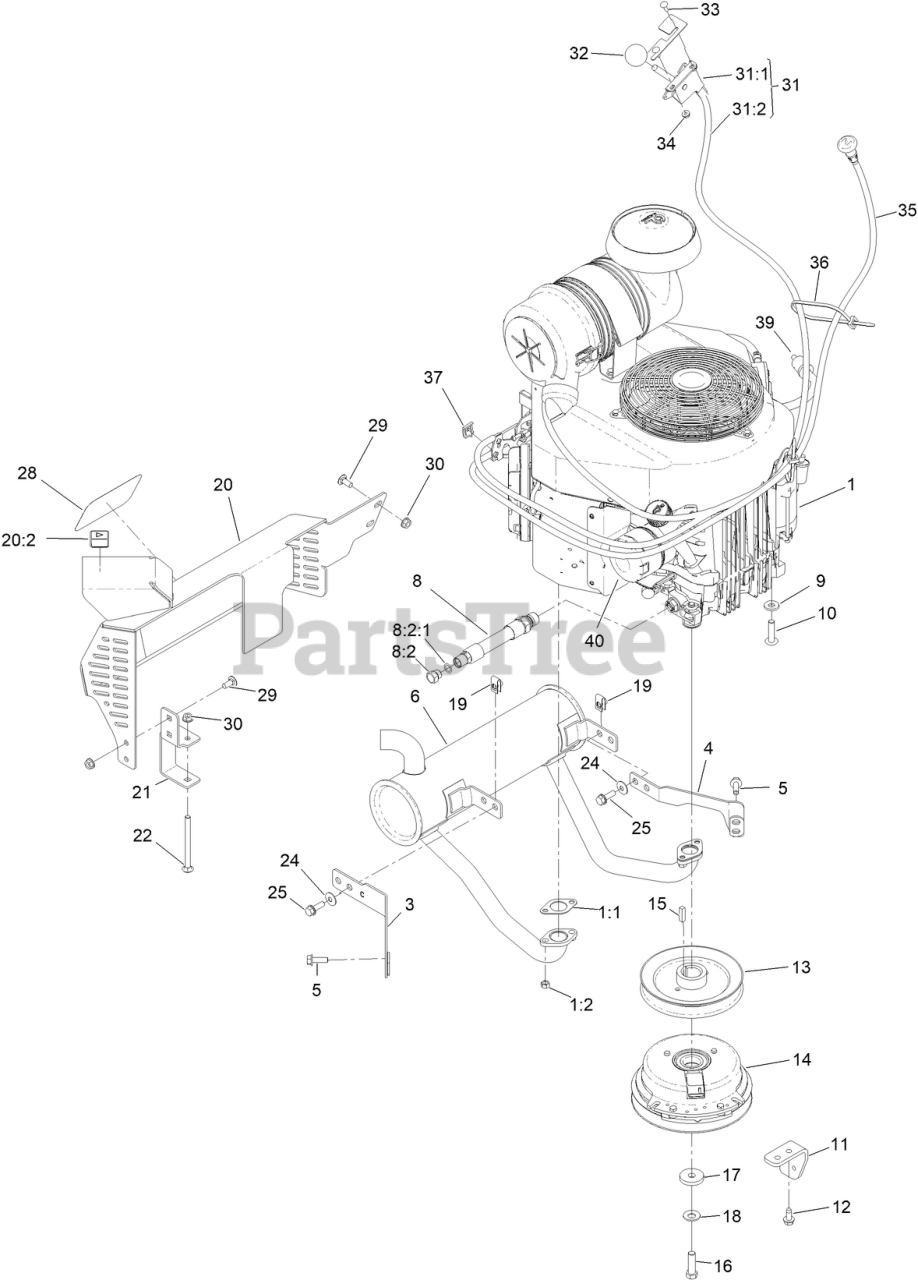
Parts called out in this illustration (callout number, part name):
1:1	GASKET-EXHAUST
3	BRACKET-MUFFLER, FRONT
4	BRACKET-MUFFLER, REAR
5	SCREW-HHF
6	MUFFLER
8	HOSE ASM
8:2	PLUG-HH
8:2:1	O-RING
9	WASHER-BELLEVILLE
10	SCREW-BHTF
11	STOP-CLUTCH
12	SCREW-HWHTF
13	PULLEY
14	CLUTCH-200CMS
16	SCREW-HH
17	WASHER-CLUTCH
18	WASHER-SPRING
19	NUT-U
20	MUFFLER GUARD ASM
20:2	DECAL-WARNING
21	BRACKET-MOUNTING, GUARD
22	SCREW-CARR
24	WASHER-BELLEVILLE
25	SCREW-HHF
28	DECAL
29	SCREW-CARR
30	NUT-HF
31	THROTTLE ASM
31:1	LEVER-CONTROL
31:2	CABLE-THROTTLE
32	KNOB-BALL
33	BOLT-CARR
34	NUT-LOCK, FLANGE
35	CABLE-CHOKE
36	TIE-CABLE
37	CLAMP-CABLE
39	FILTER-FUEL
40	FILTER-OIL
